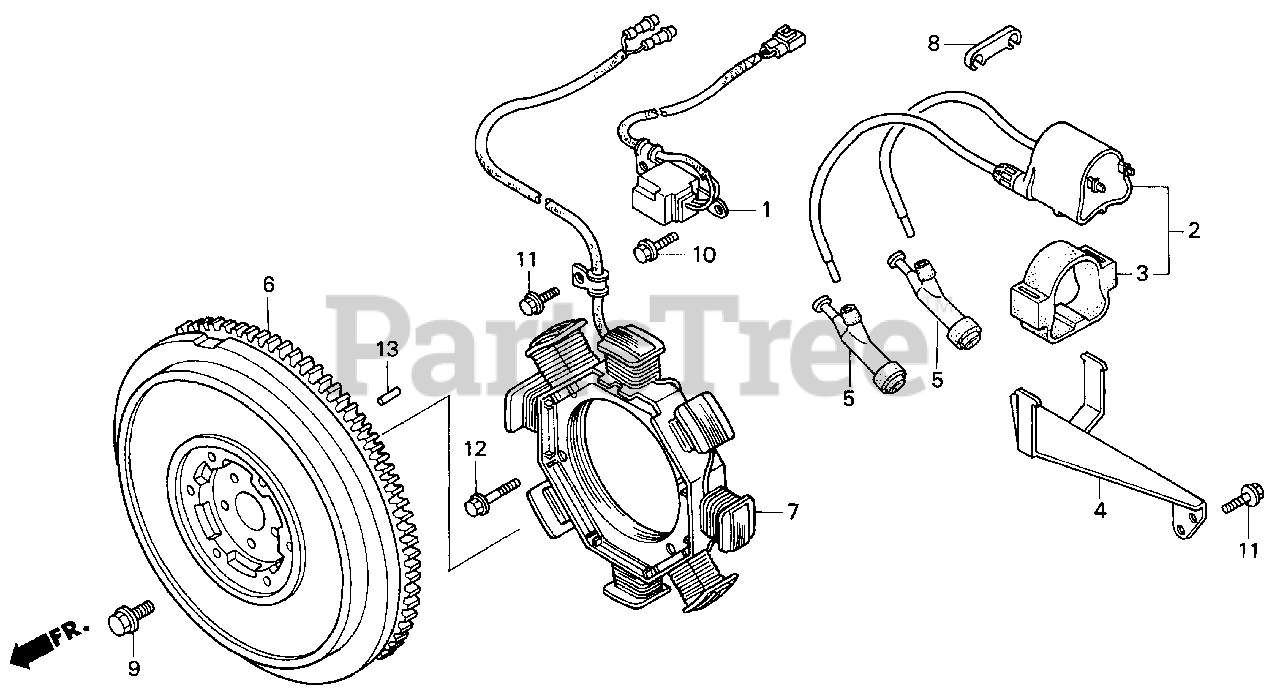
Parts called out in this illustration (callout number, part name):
1	COIL ASSY., PULSER
2	COIL ASSY., IGNITION
3	SUSPENSION, IGNITION COIL
4	BRACKET, IGNITION COIL
5	CAP ASSY., NOISE SUPPRESSOR (NICHIWA Y-EZ RTFM256)
7	COIL ASSY., CHARGE
8	CLAMP, WIRE
9	BOLT, HEX. (10MM)
10	BOLT, FLANGE (5X16)
11	BOLT, FLANGE (6X14)
12	BOLT, FLANGE (6X25)
13	PIN B, DOWEL (6X10)
